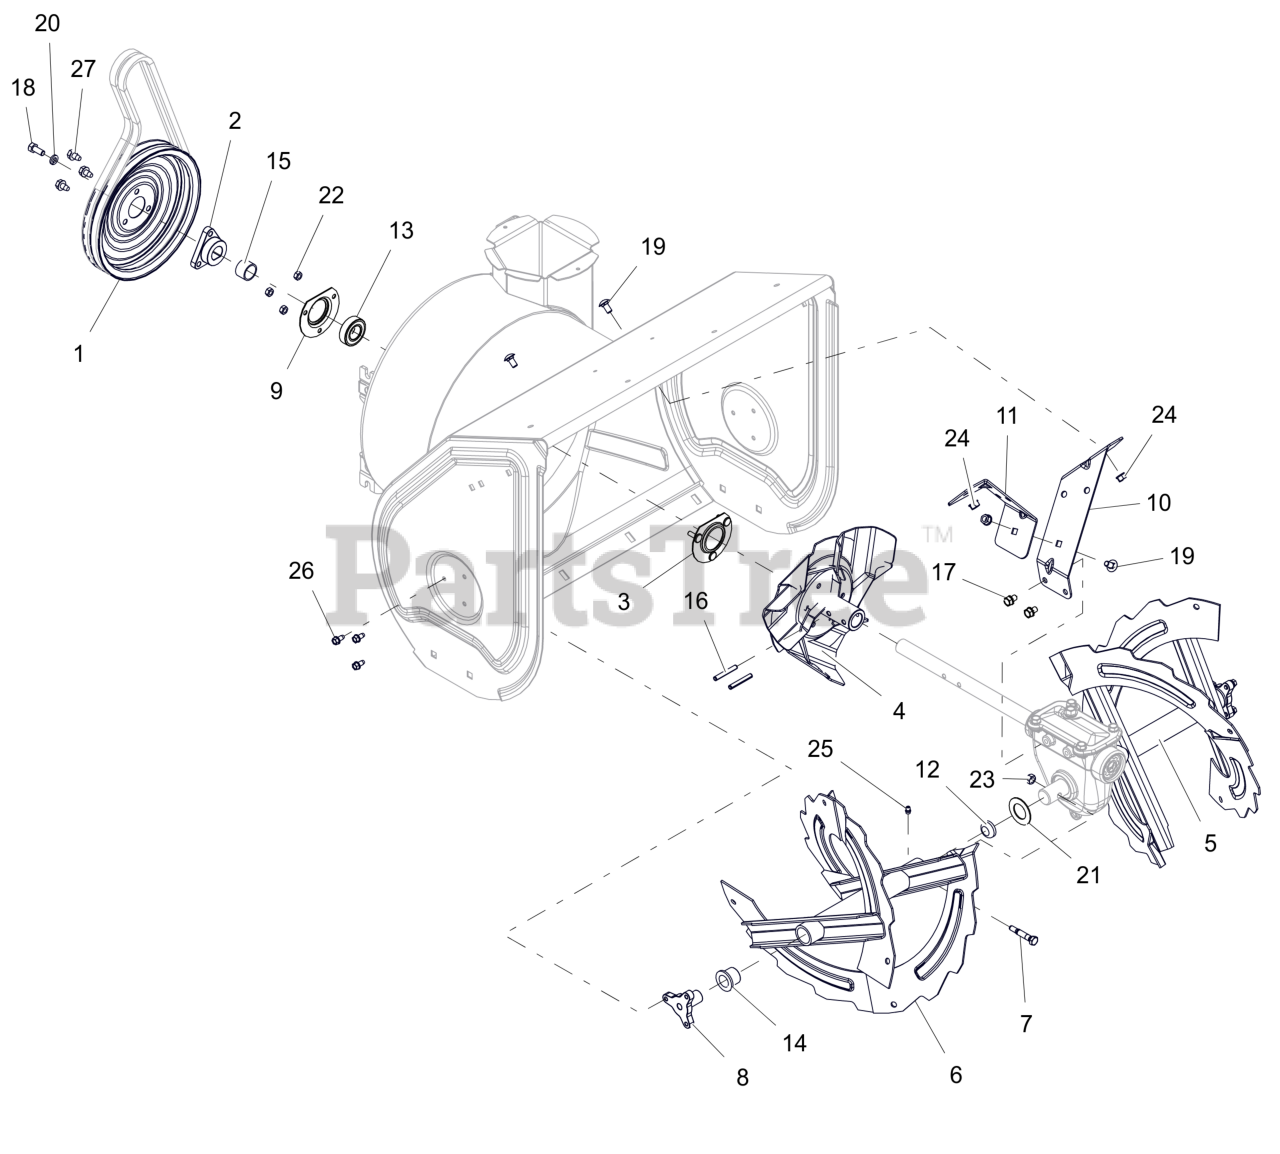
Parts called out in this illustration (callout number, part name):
1	PULLEY, SPIN FORM DUAL GROOVE
2	PULLEY HUB, D-BORE .87 PRO
3	BEARING FLANGE
4	IMPELLER, SNO - 3 BLADE 14" (ORANGE)
5	RAKE, LH W/ZERK - 24" ORANGE
6	RAKE, RH W/ZERK - 24" ORANGE
7	SHEAR BOLT SERVICE ASSEMBLY (INCLUDES NUT)
8	SUPPORT, RAKE BUSHING
9	BEARING FLANGE
10	BRKT, GEARCASE SUPPORT -LH (ORANGE)
11	BRKT, GEARCASE SUPPORT -RH (ORANGE)
12	PLUG, RAKE TUBE
13	BRG-BALL .876 X 1.750 X .50
14	BSHG-FLG, NY.778 ID X 1.018 OD
15	BSHG,SPCR .895X1.065X.693
16	PIN-ROLL .250X1.75
17	BLT, SEMS .31-18X.50 G5 ZCC
18	BLT, HEX .31-24X.750 G5 ZCC
19	BLT,RHSSN.31-18X.625 G5 ZCCP30
20	WSHR, LK-HVY .312X.097 ZCC
21	WSHR- FLT 1.010X1.755X.062 ZCC
22	NUT,LK-CTR .25-20 GA ZCC
23	NUT,LK-CTR .31-18 GA ZCC
24	NUT-LK-TOP-FLG .312-18 GF ZCC
25	ZERK,FITTING .25X.125 DRIVE IN
26	SCR-TAP .25-20X.50 HWH ZCC
27	SCR,TAP .312-18X.50 HWH TR ZCC
